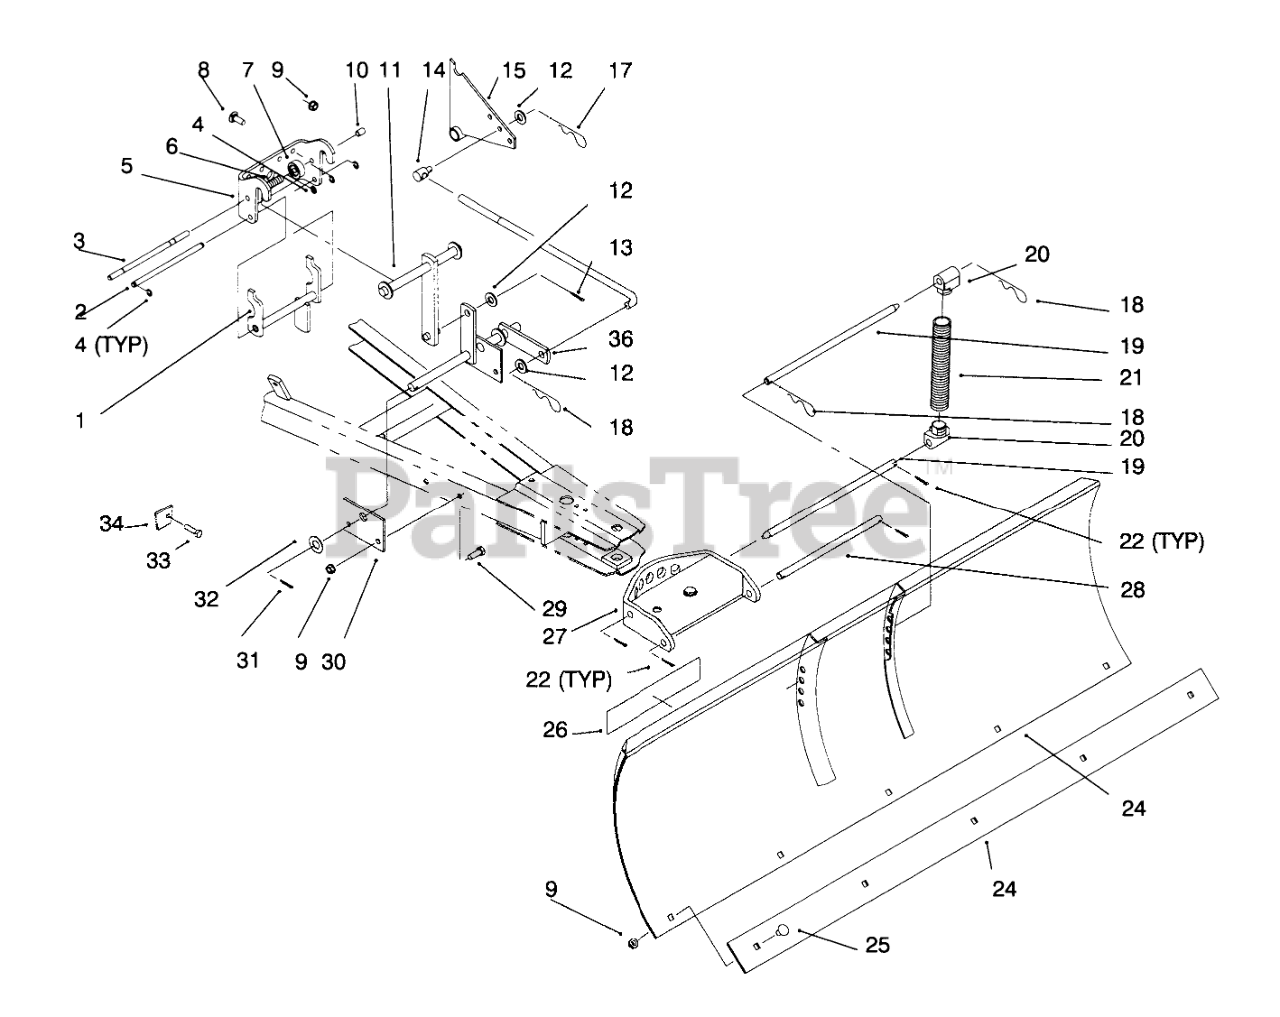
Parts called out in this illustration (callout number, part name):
1	LATCH
2	ROD-LATCH PIVOT
3	ROD-LOCK
4	RING-RETAINING
5	HITCH-FRONT
6	SPRING
8	SCREW-CARR
9	NUT-LOCK, NI
10	CAP-ROD, PLUNGER
11	Arm
12	WASHER-FLAT
13	PIN-COTTER
14	STUD-TRUNION
15	Plate
17	PIN-HAIR
18	PIN-HAIR
19	ROD-PIVOT, BLADE
20	Lug
21	Spring-Return
22	PIN-COTTER
23	BLADE ASM
24	PLATE - BLADE EDGE
25	SCREW-CARR
26	DECAL-ATTACHMENT
27	QUADRANT
28	ROD-LOWER
29	SCREW-HH
31	PIN-COTTER
32	WASHER-FLAT
33	Screw
36	ARM-LIFT
